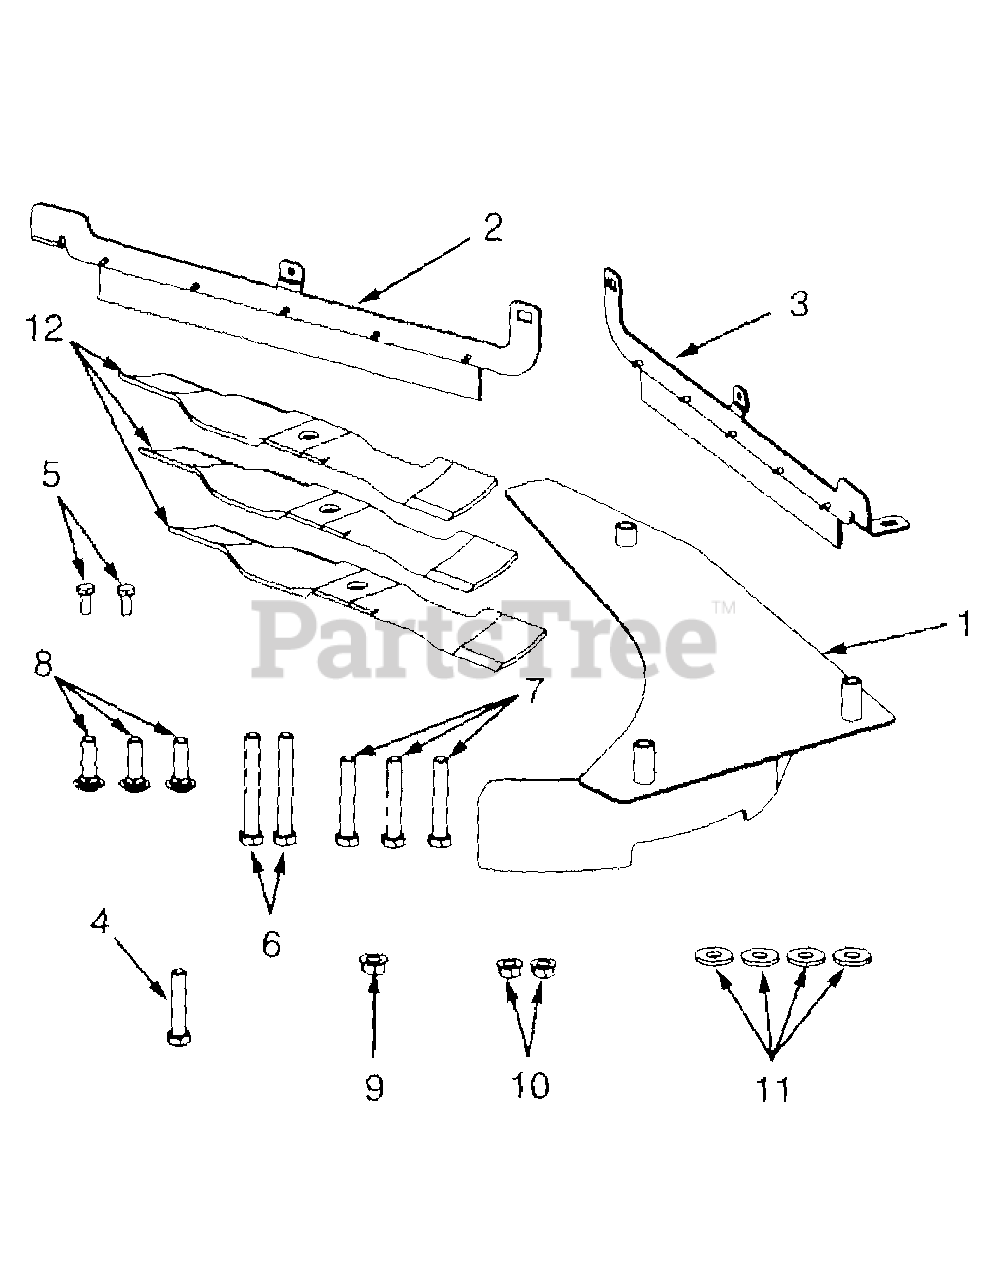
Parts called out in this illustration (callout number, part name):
4	Screw, Hex Cap, 3/8-16 x 1.5 GR5
5	Screw, Hex Cap, 1/4-20 x .62 GR5
6	Screw, Hex Cap, 3/8-16 x 2.25 GR
7	Screw, Hex Cap, 3/8-16 x 1.75
8	Bolt, Carriage, 3/8-16 x 1.0 GR5
9	Nut, Hex Flange Lock, 3/8-16
10	Nut, Hex Flange Lock, 1/4-20
11	Washer, Flat, .406 X 1.0 X .105
12	Blade, Mulching, 16.5 Lg
